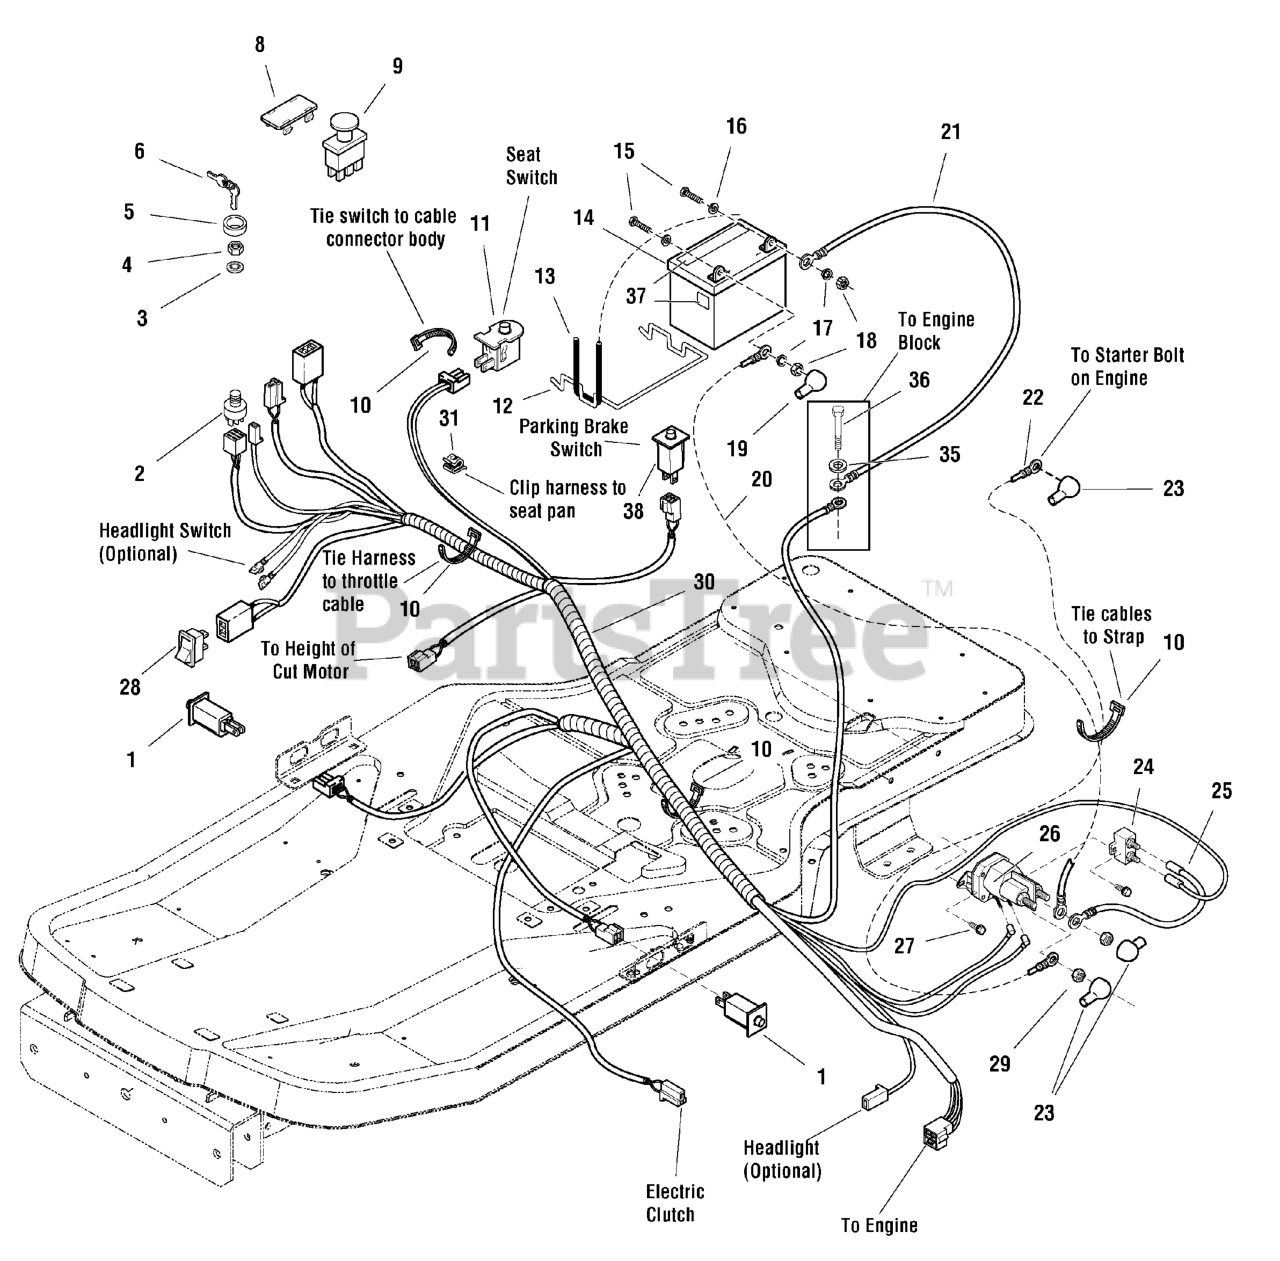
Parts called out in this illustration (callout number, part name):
1	SWITCH, Push Button
2	SWITCH ASSEMBLY, Ignition, 5/8-32 6 Pin Indak
3	LOCKWASHER, Internal Tooth, 5/8 Thin
4	NUT, Hex Flange, 5/8-32 IGN SW Die Cast
5	COVER, Ignition Switch
6	KEYS
8	PLUG, Hole
9	SWITCH, PTO, Push/Pull
10	TIE, Self Locking, .184 WD 7.31 LG
11	SWITCH, Seat, Push Button (NC)
12	BRACE, Battery, .19 DIA Wire
13	STRAP, Black Rubber, .19 SQ 7.88 OD Battery
14	BATTERY, 12 Volt 6 Cell 340CCA
15	CAPSCREW, Hex Head, 1/4-20 x 3/4, G5
16	WASHER, 1/4, .27 ID x .62 OD x .05 THK
17	LOCKWASHER, Spring, 1/4
18	NUT, Hex, 1/4-20 NC-2B
19	BOOT, Insulator, Red PVC Warning
20	CABLE, # 6 x 10 LG, Red Two-Ring Terminals
21	CABLE, 15.0 LG, Two-Ring Terminals
22	CABLE, # 6 x 15 LG, Two-Ring Terminals
23	COVER, Terminal Red PVC
24	BREAKER, Circuit, 12 Volt 20 AMP
25	WIRE, 12 Gauge, 7.9 LG
26	SOLENOID, Two Terminals, Trombetta
27	SCREW, Hex Washer Head Taptite, 1/4-20 x 1/2
28	SWITCH, Electric Height of Cut
29	NUT, Hex Keps, 5/16-24
30	HARNESS, Wiring
31	CABLE, Clip
35	WASHER, 5/16, .34 ID x 3/4 OD x .06 THK
36	SCREW, 1/4-20 x 1/2" Hex Washer Self-Tap
37	DECAL, Diehard
38	SWITCH, Push Button
